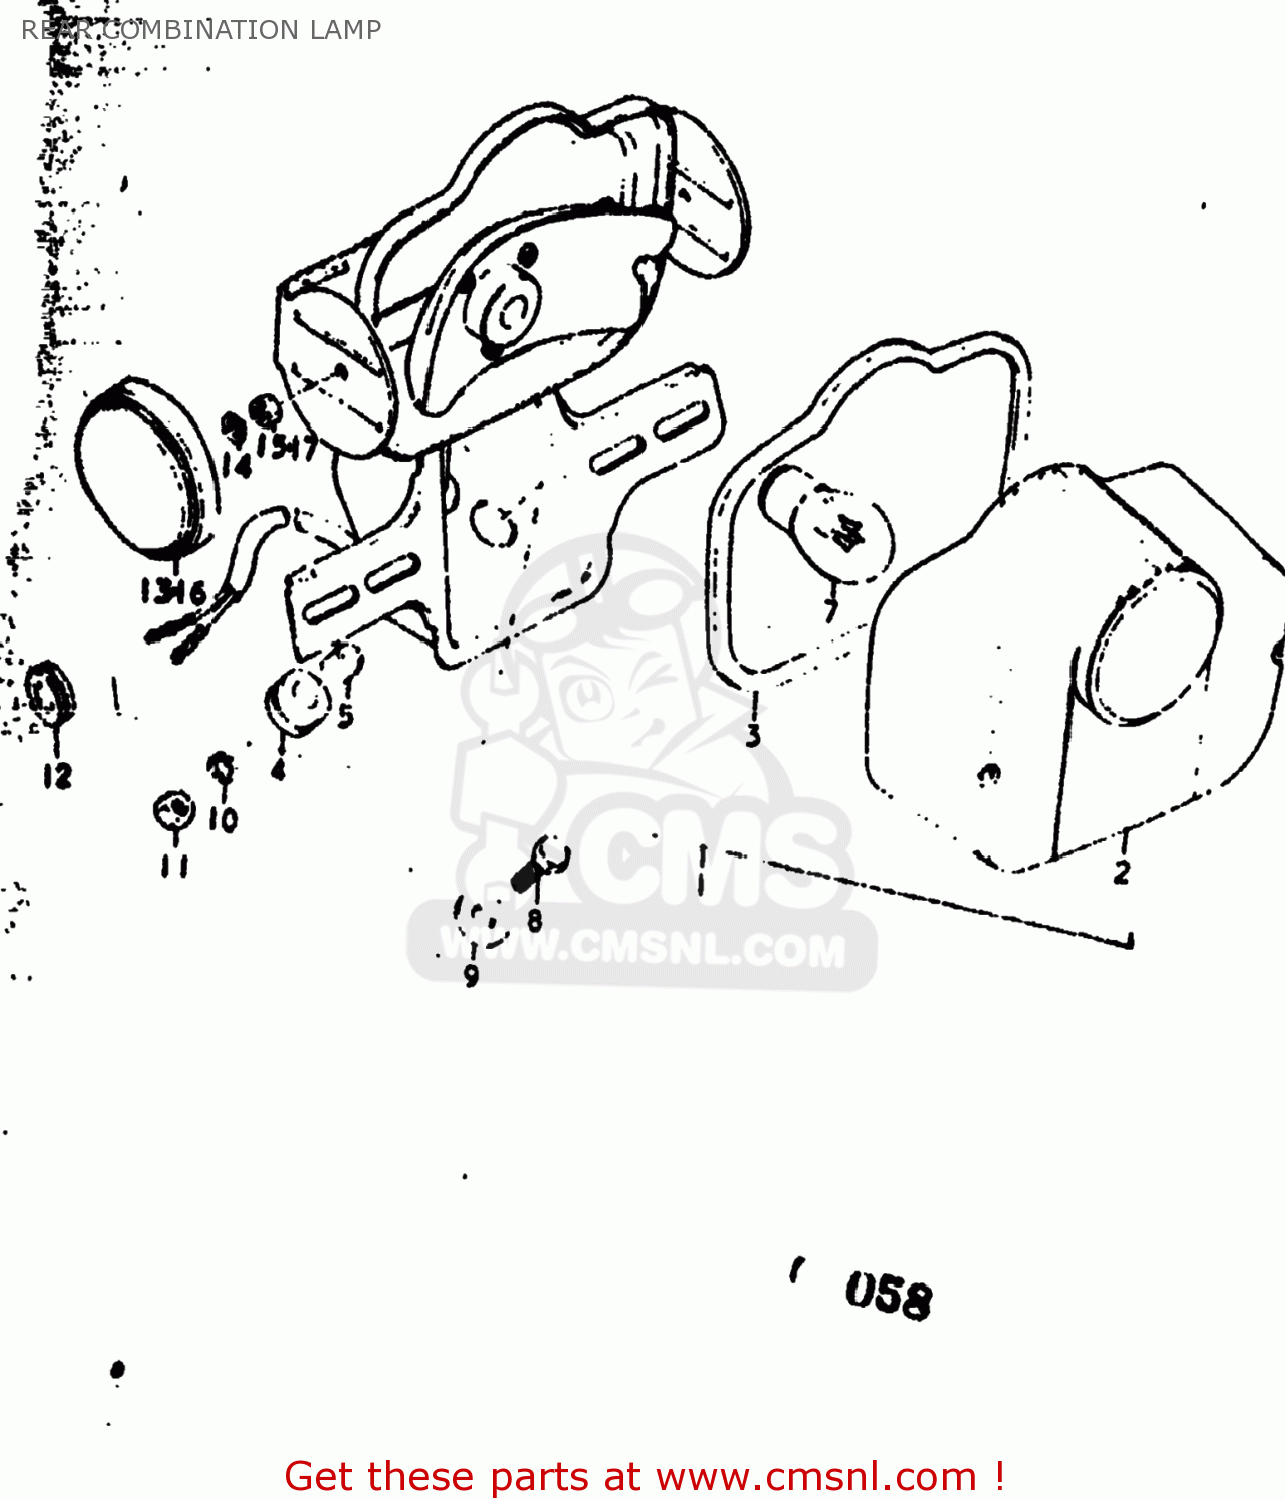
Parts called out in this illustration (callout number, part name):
1	LAMP REAR
2	LENS,REAR COMBINATION LAMP
3	GASKET (NAS)
4	CUSHION
5	SPACER,REAR COMBINATION LAMP
6	SCREW
7	BULB(6V32/3CP,STANLEY)
8	BOLT
9	WASHER
10	WASHER
11	NUT
12	GROMMET
13	REFLECTOR,REFLEX
14	LOCK WASHER
15	NUT
16	REFLECTOR,REFLEX
17	NUT
